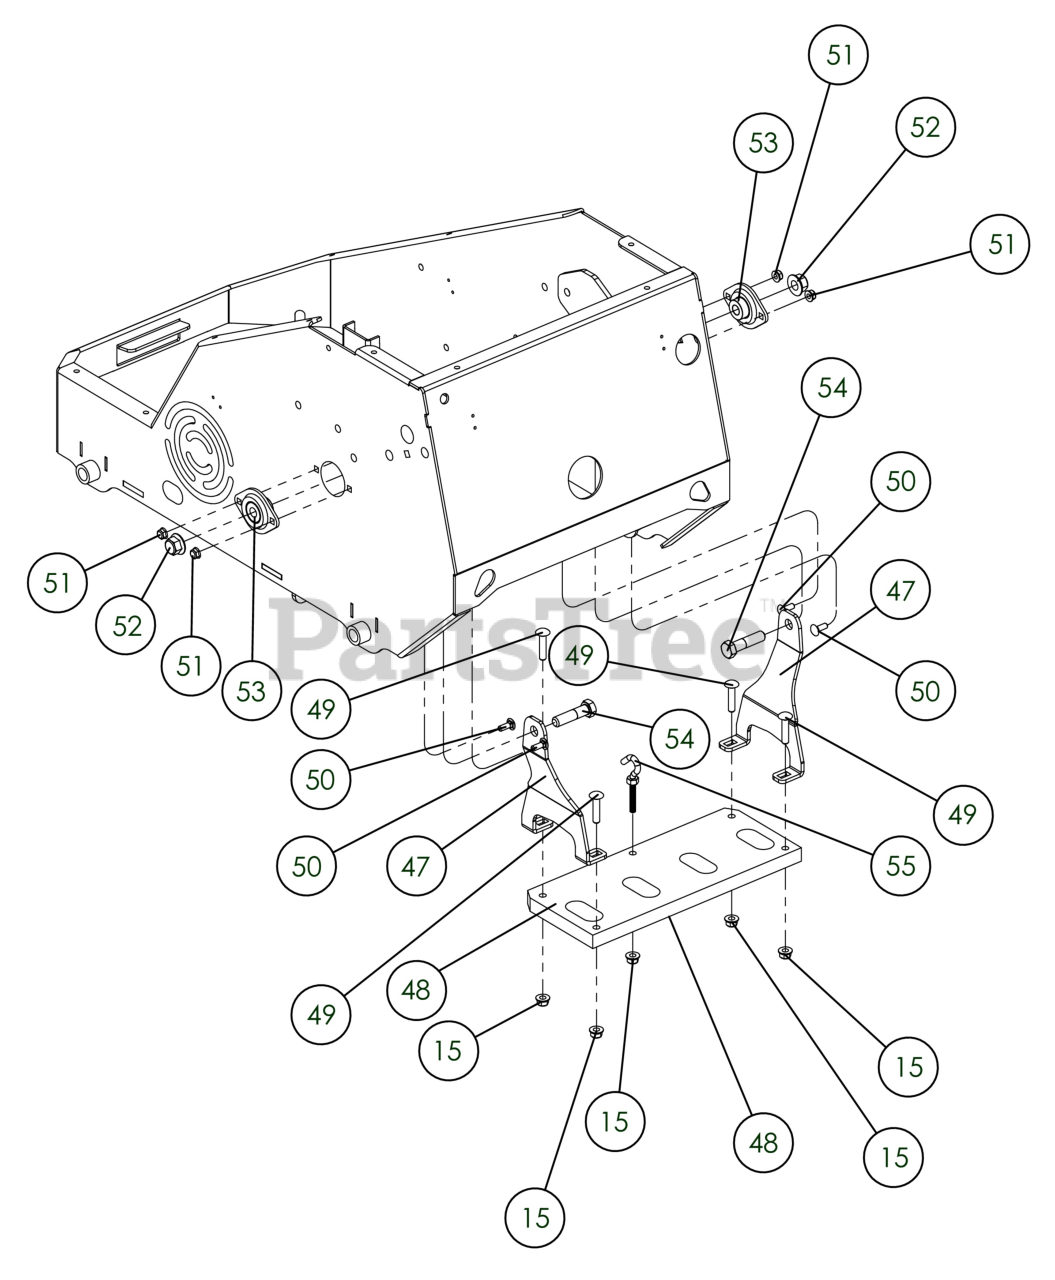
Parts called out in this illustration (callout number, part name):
15	NUT-HEX-NYLK, FLG .3125-18 ZP
47	BRKT, RETRACTOR PLATE
48	PLATE, RETRACTOR PL1801
49	BLT-RDHDSSQNK, .3125"-18 X 1.500" G5 ZP
50	BOLT CARRIAGE 1/4" X 3/4"
51	NUT-HEX-NYLK, FLG .250"-20 ZP
52	NUT-HEX-NYLK, FLG .500"-13 ZP
53	SEE: 891025-S
54	SCREWCAP 1/2"-13 X 2 GR5 ZP
55	BLT, HOOK .3125"-18 X 3.125" OAL W/NUT
